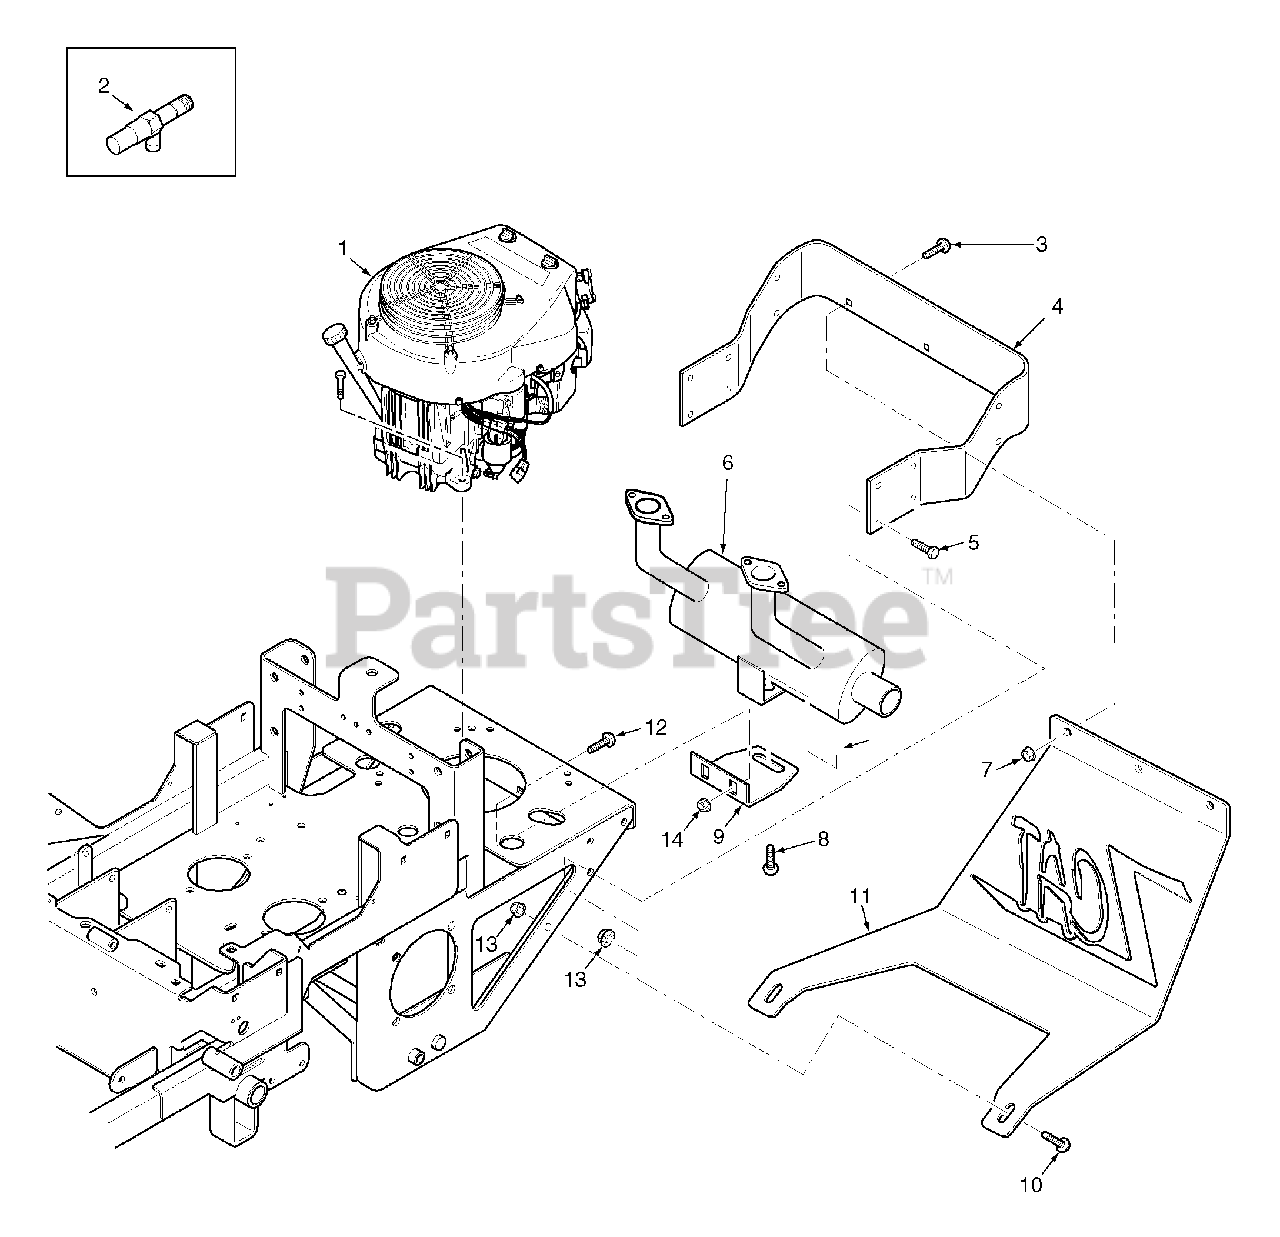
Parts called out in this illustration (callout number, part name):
1	Engine, Kawasaki 17hp (FH541V-AS36)
2	Extension, Oil Drain 4"
3	Bolt, Torx 3/8-16 x 1"
4	Bumper, Rear
5	Bolt, Hex Head 3/8-16 x 1"
6	Muffler, SZC Kawasaki
7	Nut, Serr. Flange 3/8-16
8	Bolt, 5/16-18 x 3/4" Self Tap
9	Mounting Bracket, Muffler
10	Bolt, Torx 3/8-16 x 1"
11	Skidplate
12	Bolt, Carriage 5/16-18 x 3/4"
13	Nut, Elastic Stop 3/8-16
14	Nut, Elastic Stop 5/16-18
15	Bolt, Carriage 5/16-18 x 3/4"
